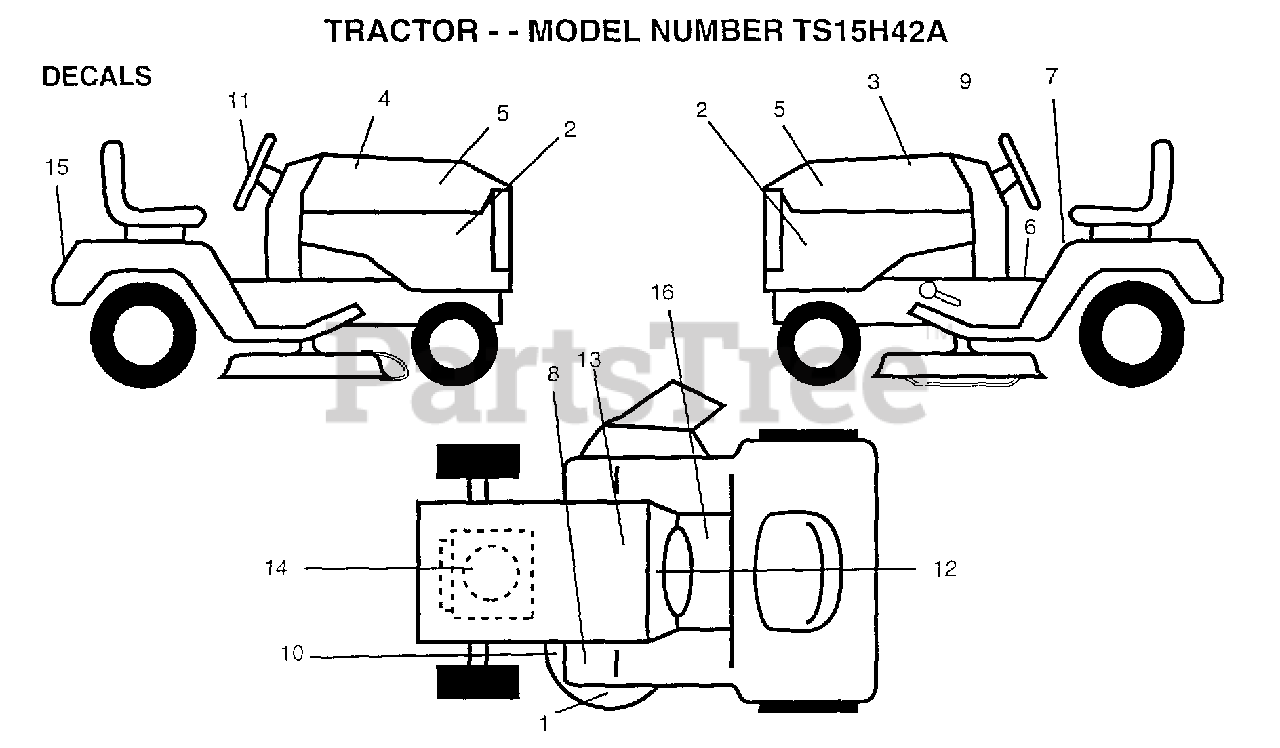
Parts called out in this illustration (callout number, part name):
2	DECAL.ONAN.PNL.15
3	DECAL HOOD LH
4	"DECAL HOOD,RH"
5	NAMEPLATE.HUSK.LG
6	DECAL BRAK PARK
7	DECAL
10	DECAL
11	DECAL.INS.STG.WHL
12	DECAL.DASH.INST.
13	DECAL.BTRY.DANGER
14	DECAL.ONAN.15HP.
15	DECAL.FEND.YT/GT
16	DECAL SADLE HYDRO
